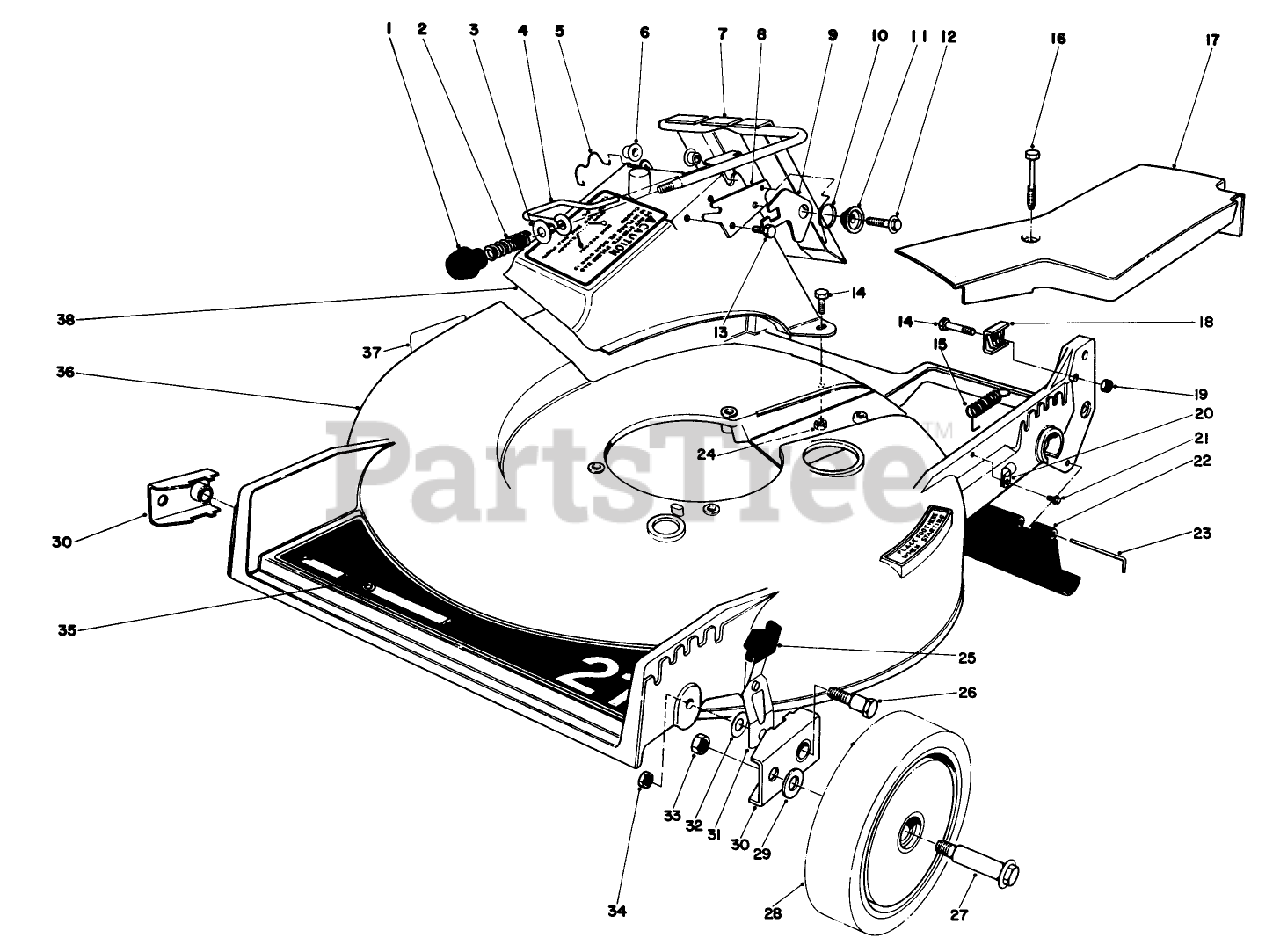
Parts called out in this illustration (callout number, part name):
2	Spring Compression
3	WASHER-FLAT
4	DOOR LATCH
5	Door Retainer
6	BUSHING-NYLON
8	DOOR LATCH PLATE
9	Latch-Door
10	Spring-Torsion
11	Latch Spacer
13	SCREW-HWH
14	SCREW-HH
15	IDLER SPRING
16	SCREW-HWH
18	CLAMP-CABLE
19	NUT-JAM
20	CLAMP-CABLE
21	SCREW-HWH
23	ROD-SHIELD
24	NUT-LOCK, NI
25	KNOB-ARM
26	PIVOT SCREW
27	BOLT-WHEEL
29	WASHER
32	WASHER-PIVOT
37	DECAL-DANGER
38	DISCHARGE CHUTE *B
